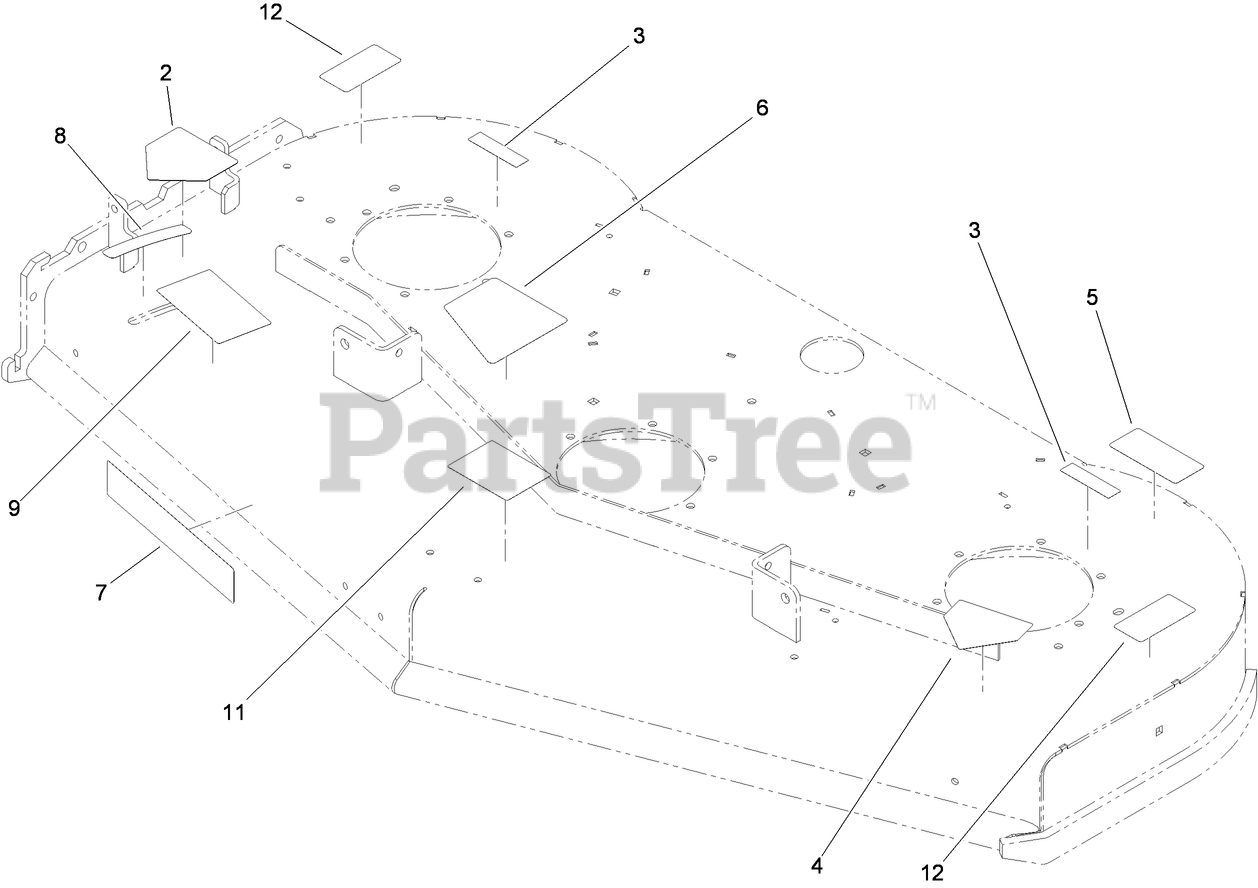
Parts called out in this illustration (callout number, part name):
2	DECAL-DANGER
3	DECAL-COVER, MISSING
4	DECAL-DANGER
5	DECAL-TORQUE
6	DECAL-TENSION, BELT
8	DECAL-SETTING, BAFFLE
9	DECAL-ADJUSTMENT, BAFFLE
11	DECAL-SCALP, ANTI
12	DECAL-ROTATING PARTS
